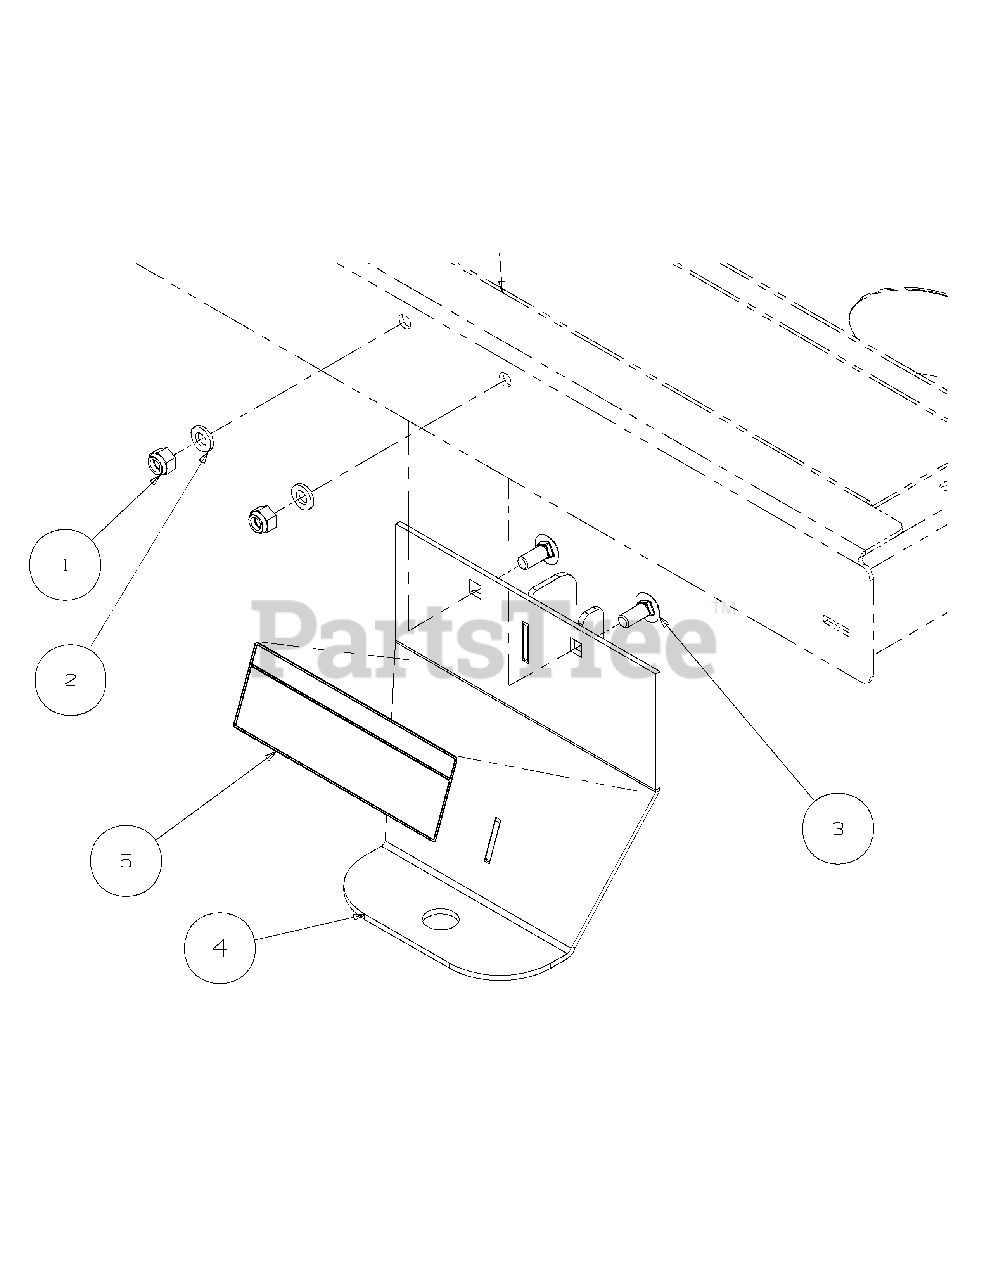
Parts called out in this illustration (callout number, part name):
1	Nylock Nut, 5/16-18
2	Flat Washer, .320 ID x .591 OD x .078
3	Carriage Bolt, 5/16-18 x .75
4	Hitch
5	Decal, Hitch Warning
